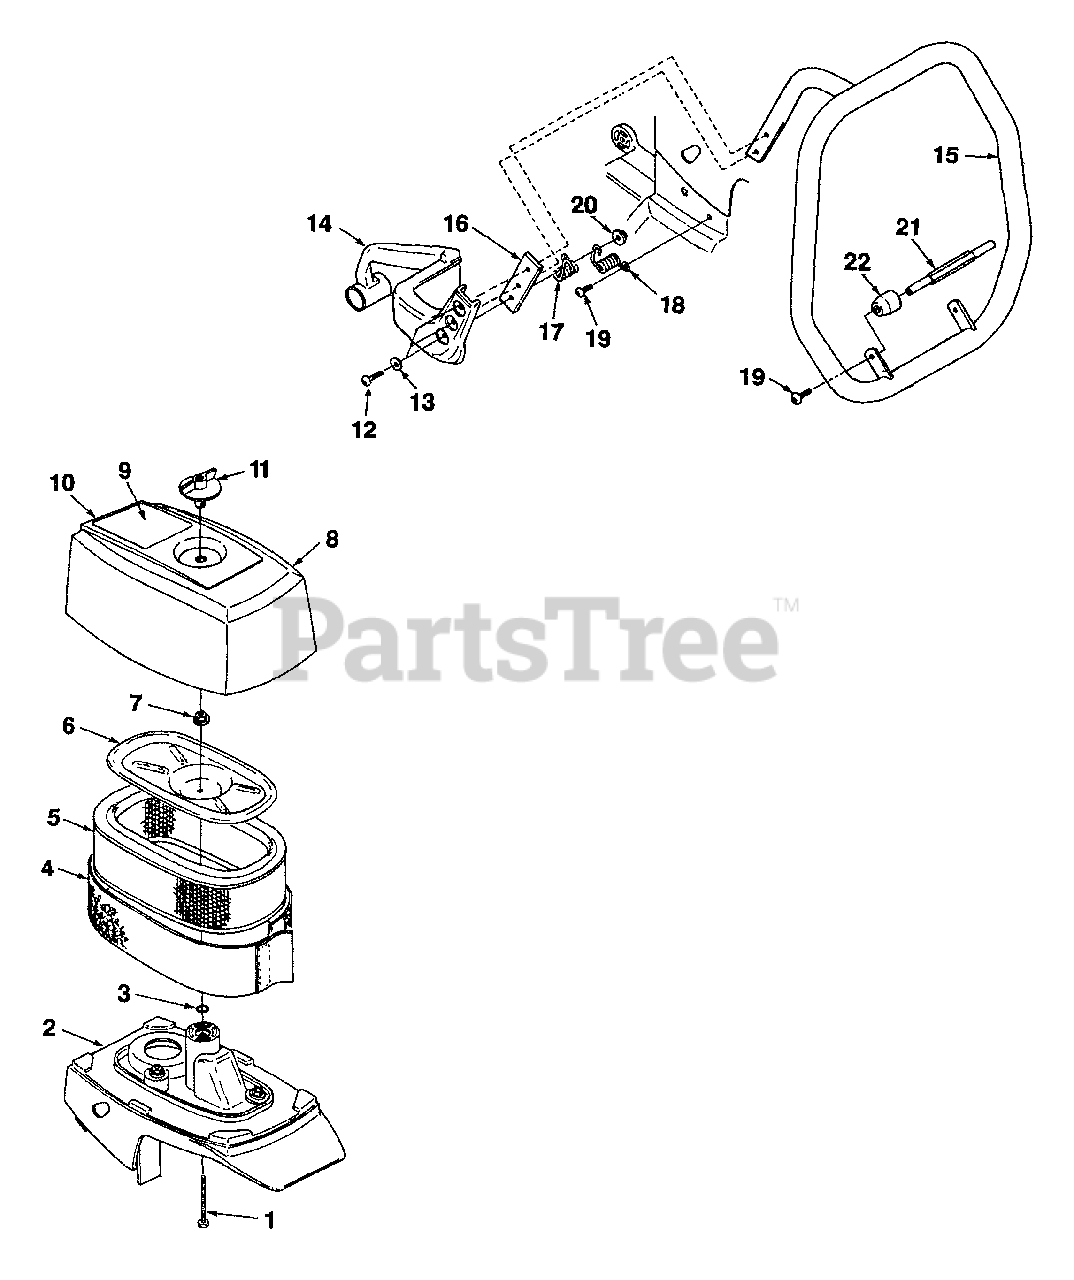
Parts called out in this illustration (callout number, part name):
1	SCREW-Hex Cap (10-24 X 1 3/4")
2	COVER-Cylinder
4	PREFILTER-Felt
5	ELEMENT-Air Filter
6	COVER-Air Filter Element
7	NUT-Hex
8	COVER-Air Filter
9	DECAL-Warning (Eng.)
10	DECAL-Warning (French)
11	KNOB & INSERT
12	SCREW-Truss Hd. (10-24 X 3/4")
13	WASHER (#12-11/16)
14	HANDLE-Rear
15	HANDLE BAR
16	BRACKET-Mounting
17	SPRING-Isolation (Small)
18	SPRING-Isolation (Large)
19	SCREW-Torx Hd. (10-24 X 1/2")
20	NUT-Hex (10-24)
21	SPACER
22	ISOLATOR-Vibration
